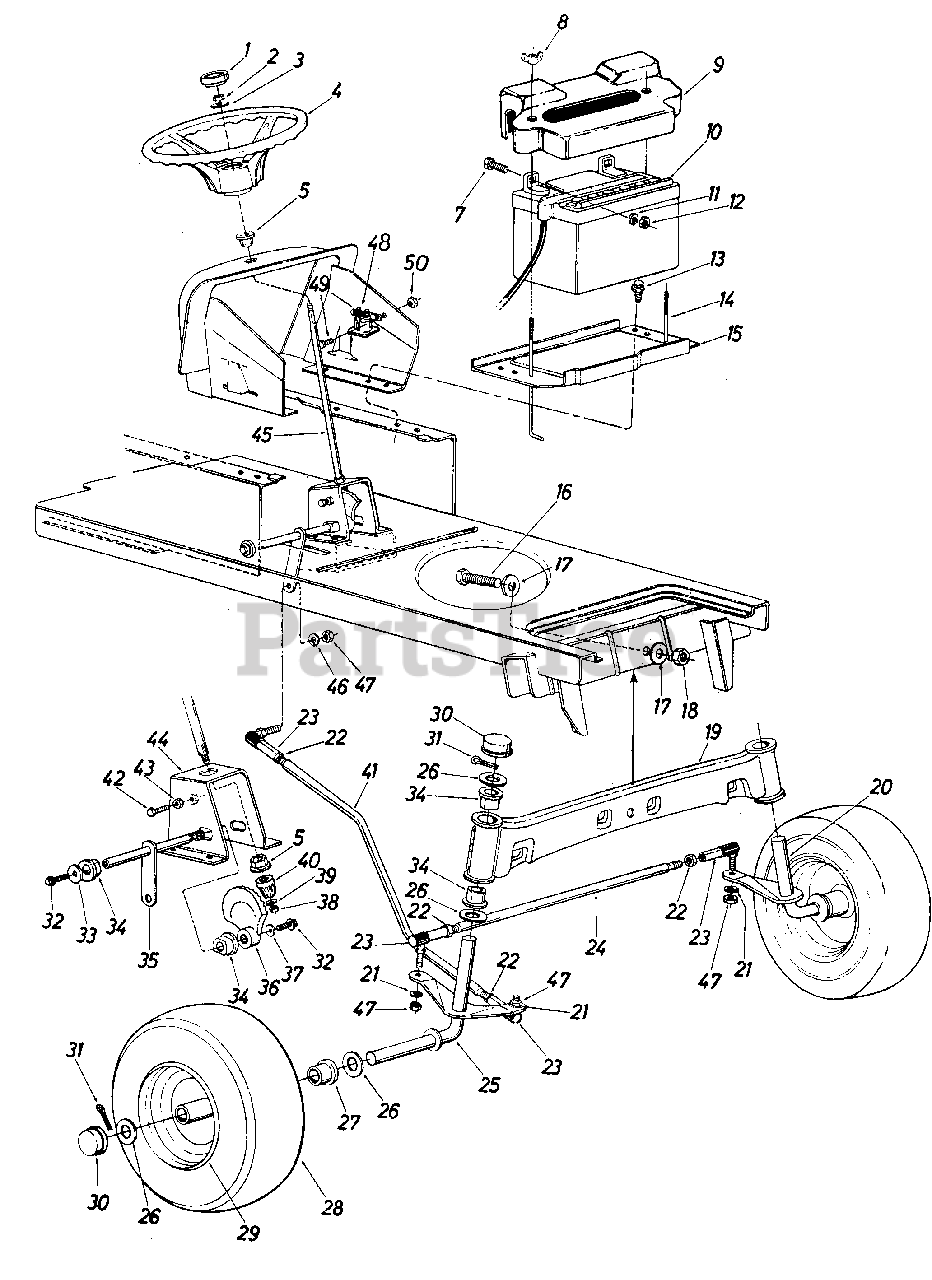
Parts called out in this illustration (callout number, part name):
1	Steering Wheel Cap
2	Hex Cent. L-Nut 5/16-18 Thd.
3	Bell-Wash. 5/16" I.D. x .87" O.D. x .060
4	Steering Wheel
5	Plastic Hex Bearing 5/8" 1. D.
7	Hex Scr. 1/4-20 x .62" Lg.
8	Wing Nut Plastic 1/4-20 Thd.
9	Battery Cover
10	12-V Battery
11	L-Wash. 1/4" Scr.*
12	Hex Nut 1/4-20 Thd.*
13	Hex Thd Rolling Scr. 1/4-20 x .50" Lg.
14	Battery Hold Down Rod
15	Battery Plate
16	Hex Scr. 5/8-18 x 2.50" Lg.*
17	Flat Wash. .66" I.D. x 2.25" O.D. x .17
18	Hex Cent. L-Nut 5/8-18 Thd.
19	Front Pivot Bar Ass'y.
20	Front Axle Ass'y. L. H .
21	L-Wash. 3/8" Scr.*
22	Hex Jam Nut 3/8-24 Thd.
23	Ball Joint Ass'y.
24	Tie Rod
25	Front Axle Ass'y. R.H.
26	Fl-Wash. .780 I.D. x 1.59 O.D
27	Flange Bearing
28	Front Wheel Ass'y. Comp.
29	Front Wheel Rim Only
29	Air Valve
29	Grease Fitting
30	Dust Cover
31	Cotter Pin 5/32" Dia. x 1.00" Lg.*
32	Hex Scr. 3/8-24 x .75" Lg. Grade 5
33	Fl-Wash. 3/8 I.D. x 1.25 O.D. x .090
34	Flange Double"D" Brg. .753 I.D.
35	Steering Arm Shaft Ass'y.
36	Side Gear Steering
37	Bell-Wash. 3/8" I.D.
38	Hex Cent. L-Nut 5/16-24 Thd.
39	Fl-Wash. 5/16" I.D. x .62 O.D. x .059
40	Pinion Gear Steering
41	Drag Link
42	Hex Nylon Scr. 3/8-16 x 1.25" Lg.
43	Hex Nut 3/8-16 Thd.*
44	Steering Gear Su p. Ass'y.
45	Steering Shaft
46	L-Wash. 3/8" Scr.*
47	Hex Nut 3/8-24 Thd.*
48	Solenoid
49	Hex Bolt 1/4-20 x .50" Lg.*
50	Hex Sems Nut 1/4-20 Thd.
